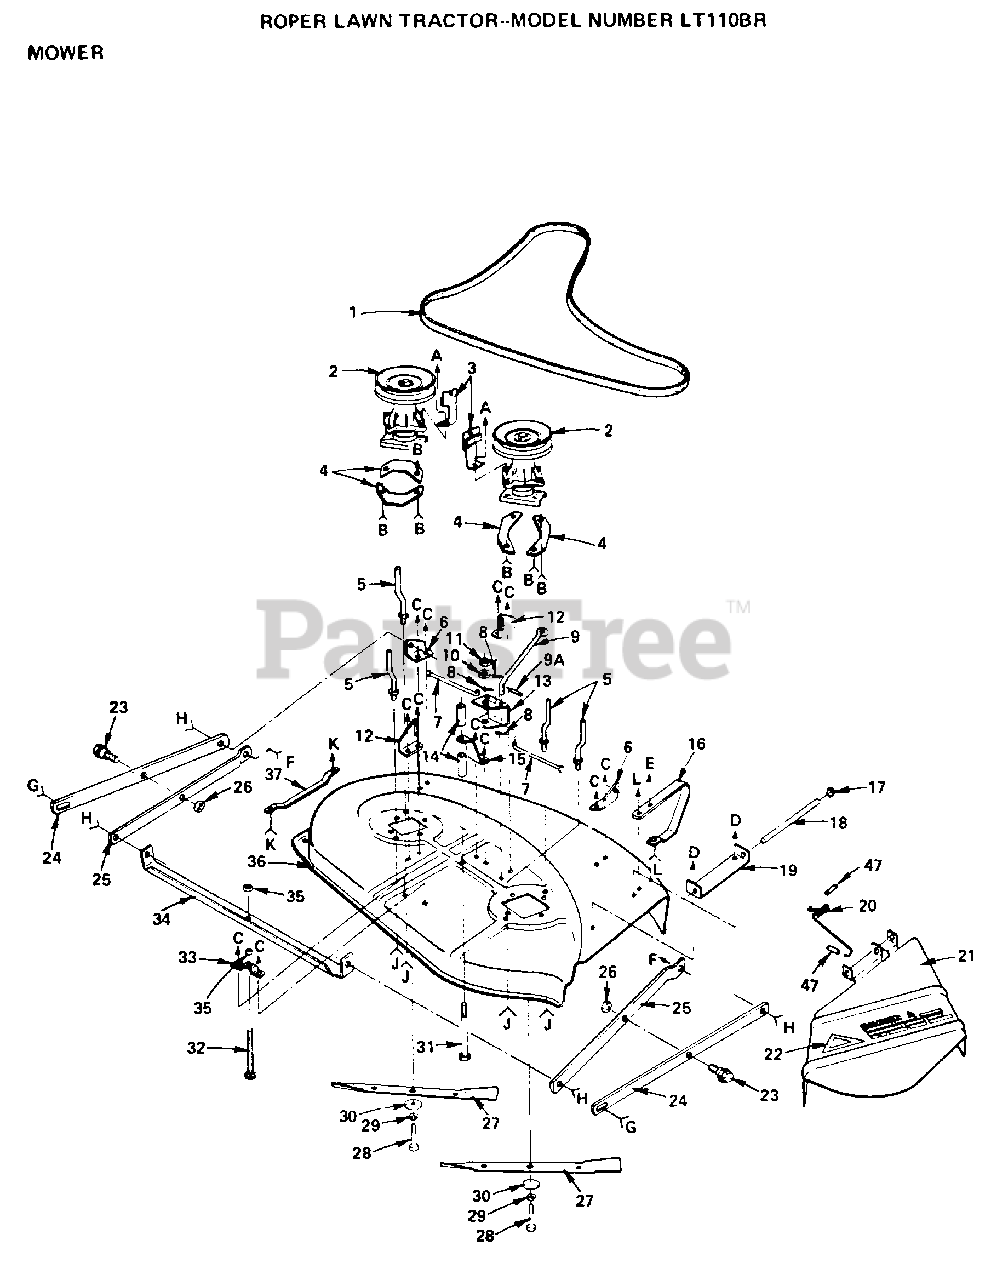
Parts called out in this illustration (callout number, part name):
4	SUPPORT PLATE LT
5	BELT KEEPER LT
6	BRACKET FRONT LTV
7	ROD BRAKE LTV
8	COTTER PIN
9	ROD BRAKE LTV
10	WASHER
11	LOCKNUT
12	BRACKET LIFT LTV
13	BRACKET PIVOT LTV
14	SPACER BRAKE LTV
15	BRACKET SUPT LTV
18	ROD HINGE LTV
20	SPRING M
23	BOLT SHOULDER LTV
24	ARM SUSPENS. LTV
25	ARM SUSPENS. LTV
28	BOLT.3/8-24X1-1/2
29	LOCKWASHER
30	WASHER
34	CROSSBAR LTV
35	NUT.HEX.3/8-16UNC
37	RUNNER-LH M
47	CAP-SLEEVE LT
